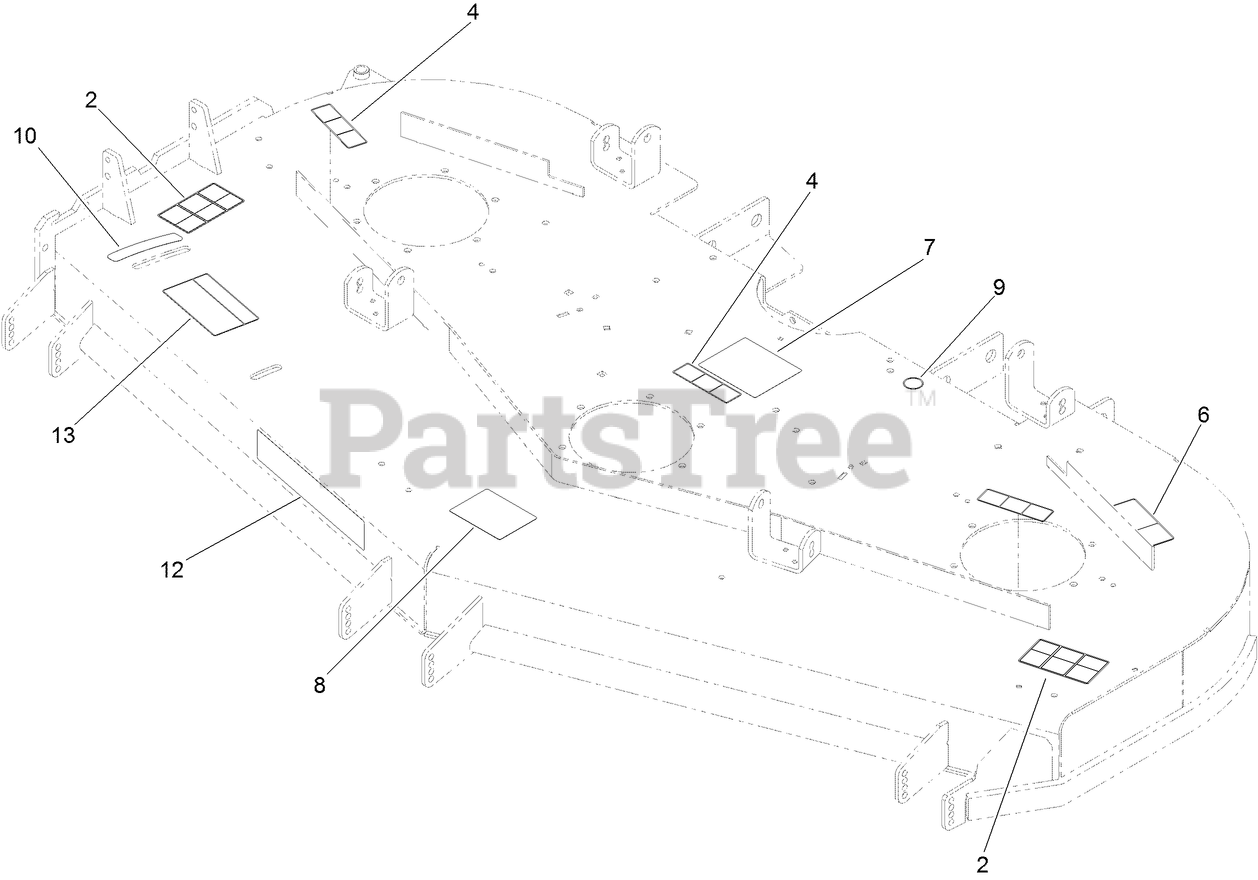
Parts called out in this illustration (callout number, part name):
2	DECAL-DANGER
4	DECAL-COVER, MISSING
6	DECAL-TORQUE, BLADE BOLT
7	DECAL-ROUTING, BELT
8	DECAL-SCALP, ANTI
9	DECAL-GREASE
10	DECAL-SETTING, BAFFLE
13	DECAL-ADJUSTMENT, BAFFLE
